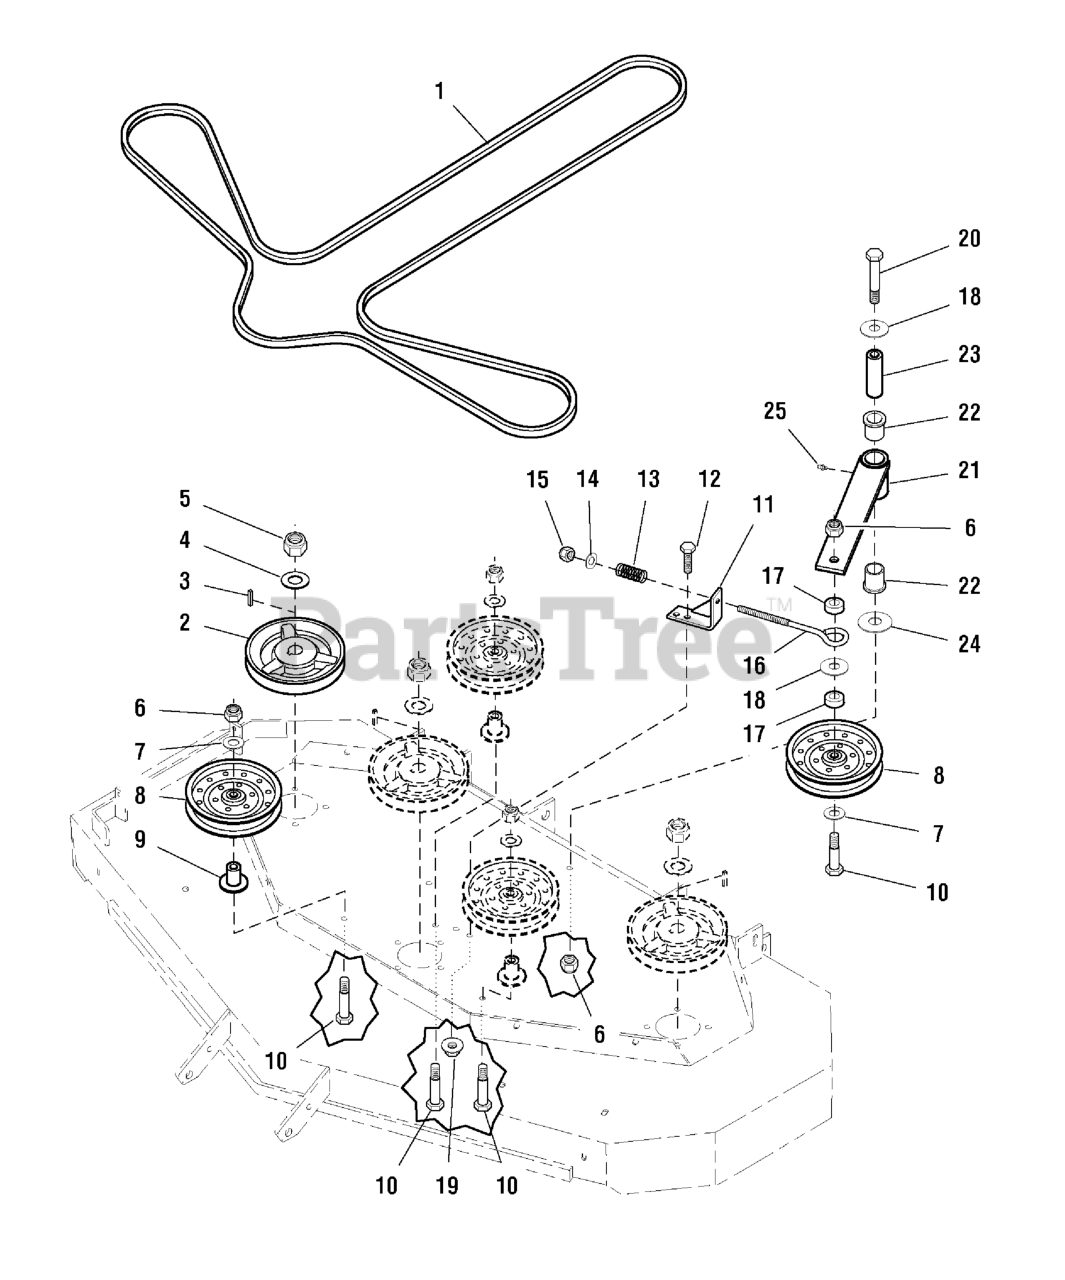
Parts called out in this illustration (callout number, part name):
1	BELT, 5V, 175.90EL, LG ARAMID, WRPD, RC
2	SPINDLE PULLEY
3	KEY, 1/4 SQ. X 1-1/4
4	WASHER, Spring
5	NUT, 5/8-18 Hex Nylon Lock
6	NUT, 1/2-13 HEX NYLON LOCK
7	WASHER, 1/2 SAE
9	IDLER MOUNT
10	BOLT, 1/2-13 X 3" GD5 CZ
11	WELD, SPRING ANCHOR
12	BOLT, 3/8-16 X 1" GD5 CZ
13	SPRING, Compression
14	WASHER, 3/8 SAE
15	NUT, 3/8-16 HEX NYLON LOCK
16	EYEBOLT, 3/8" x 8"
17	SPACER, .52 x 1.00 x .44
18	WASHER, 1/2" USS
19	NUT, 3/8-16 Hex Serrated Flange
20	BOLT, 1/2-13 x 4-1/2
21	IDLER ARM
22	BUSHING, FLANGE
23	SPACER, .52 x 1.00 x 3.50
24	WASHER, 5/8" SAE
25	GREASE FITTING
